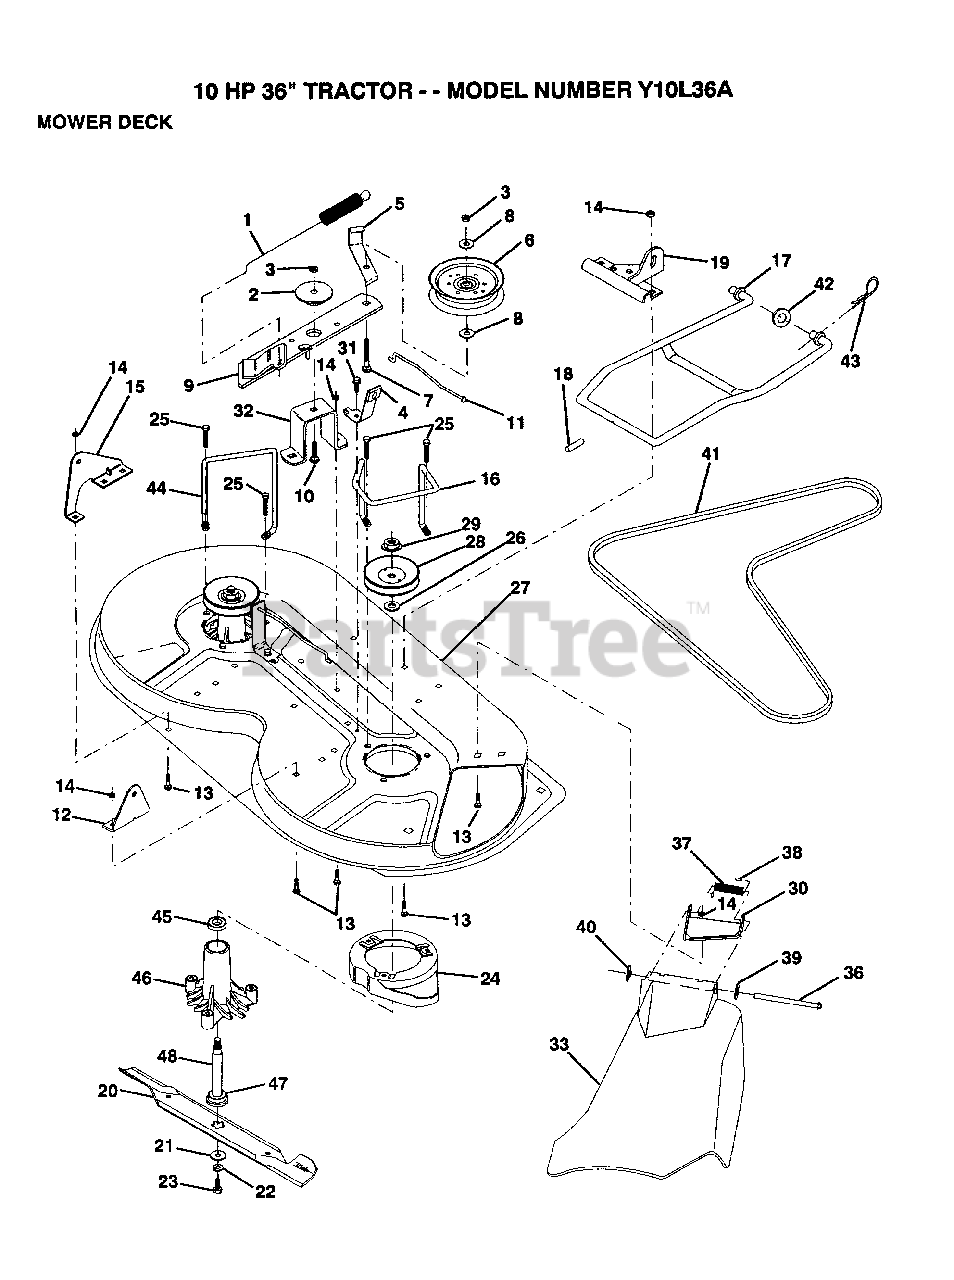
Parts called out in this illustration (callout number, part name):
2	SPACER RETAINER
4	BRAKE ASM
5	IDLER BELT GUIDE
6	PULLEY IDLER
7	BOLT
8	WASHER
10	BOLT D
11	BRAKE ROD
12	"BRKT,LIFT REAR"
13	BOLT
15	"BRKT,LIFT REAR LH"
17	MOWER LINK STAB
18	"PIN,GROOVE"
19	"BRKT,LINK STABILI"
21	WASHER BLADE
23	BLADE BOLT
26	WASHER
31	SCREW LT
32	"SUPT,IDLER ARM"
36	HINGE ROD
37	SPRING TORSION
38	CAP-SLEEVE LT
39	WASHER
40	NUT PUSH M
41	V-BELT.PRIM.78.5.
43	RETAINER.SPRING
45	BEARING
46	HSG ASM MANDREL
47	BEARING.BALL
